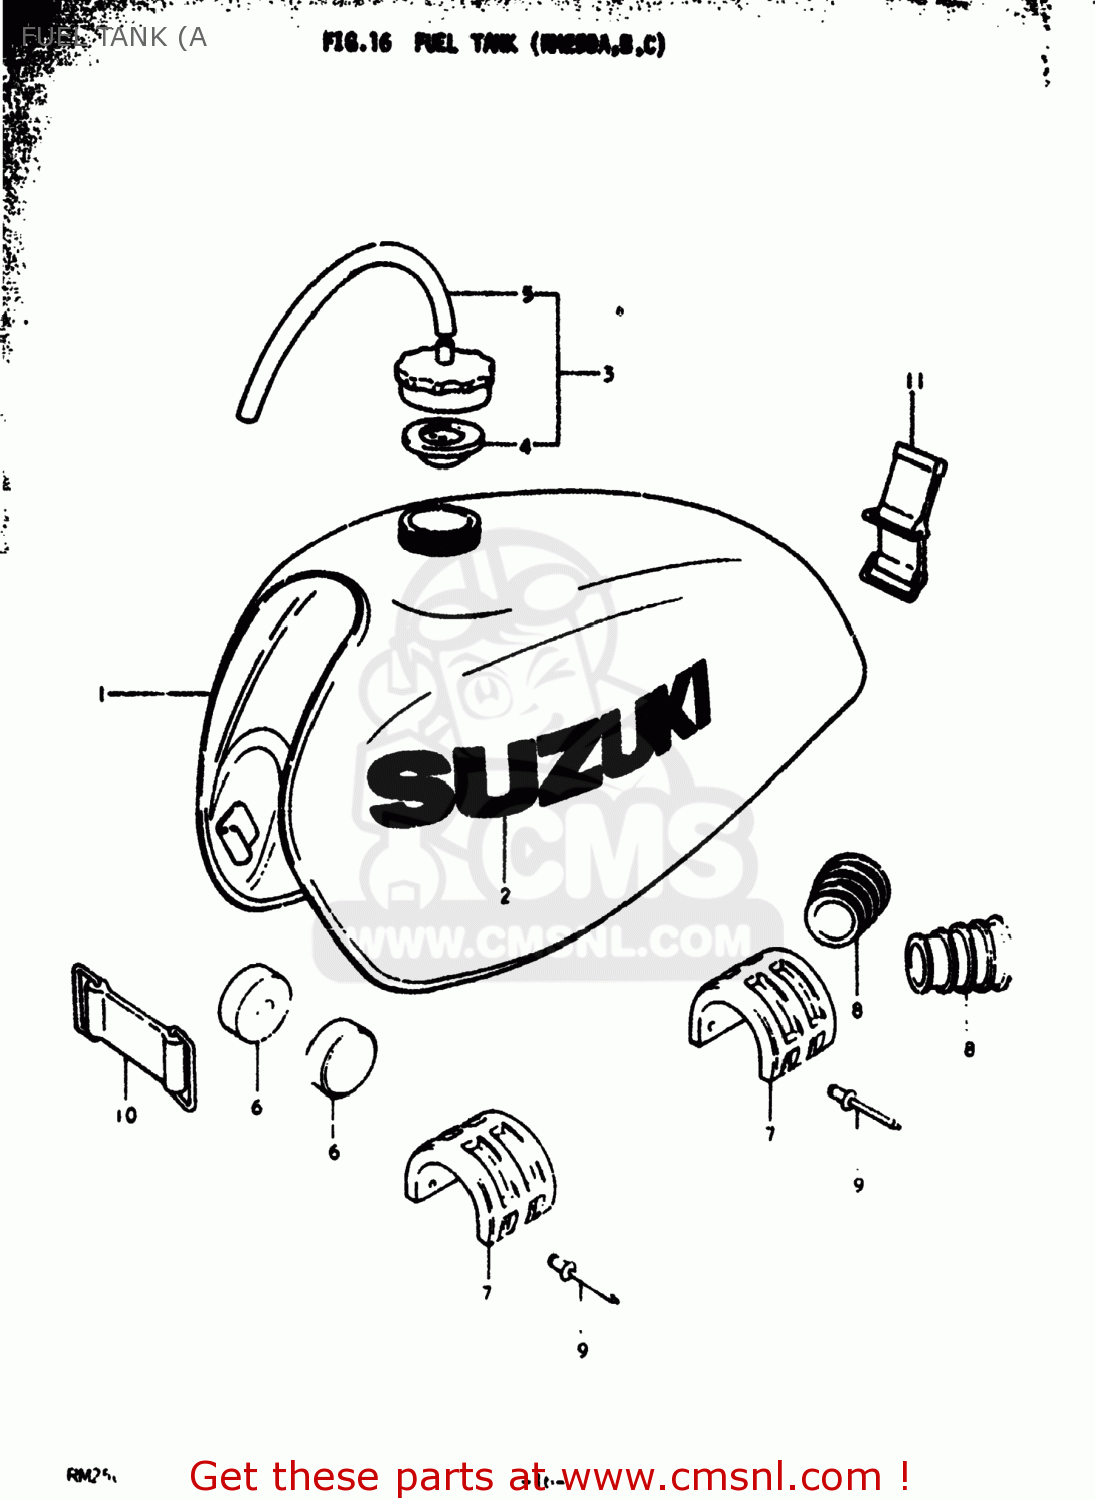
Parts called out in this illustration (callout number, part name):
1	TANK ASSEMBLY,FUEL
2	EMBLEM
3	CAP ASSY,FUEL TANK FILLER
4	GASKET,FUEL TANK CAP (NAS)
5	HOSE
6	CUSHION
7	CUSHION,FUEL TANK,CENTER
8	CUSHION,FUEL TANK,FRONT
9	RIVET
10	BAND
11	BAND
